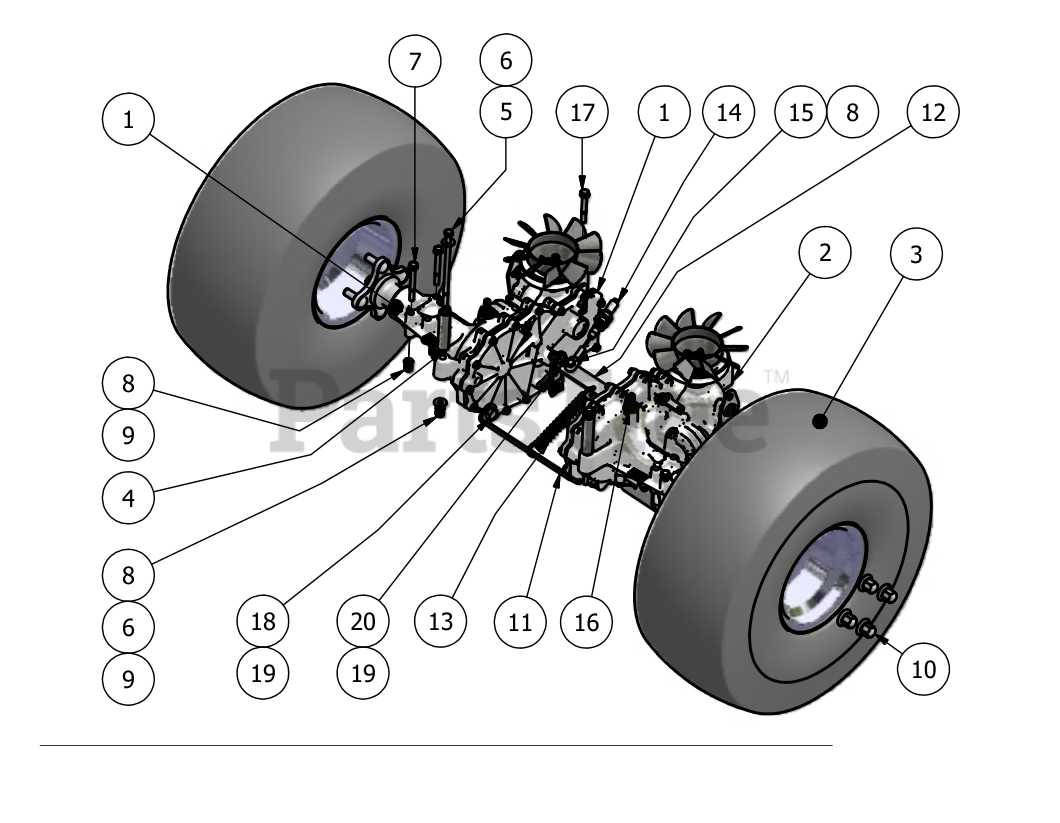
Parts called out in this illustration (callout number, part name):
2	Axle-Right
3	Tire and Rim
4	3 1/4" Transaxle Spacer
5	5/16" x 6" Hex Bolt
6	5/16 Lock Washer
7	5/16" x 3" Hex Bolt
8	5/16 Hex Nut
9	5/16" Flat Washer
10	1/2" Acorn Lug Nut
11	Crossover Brake Bracket
12	Crossover Bar
14	Brake Cable
15	5/16" x 3/4" Hex Bolt
16	45 degree fitting
17	5/16" x 2 1/2" Hex Bolt
18	3/8" x 2" Hex Bolt
19	3/8" Nylock Nut
20	3/8" x 1" Hex Bolt
